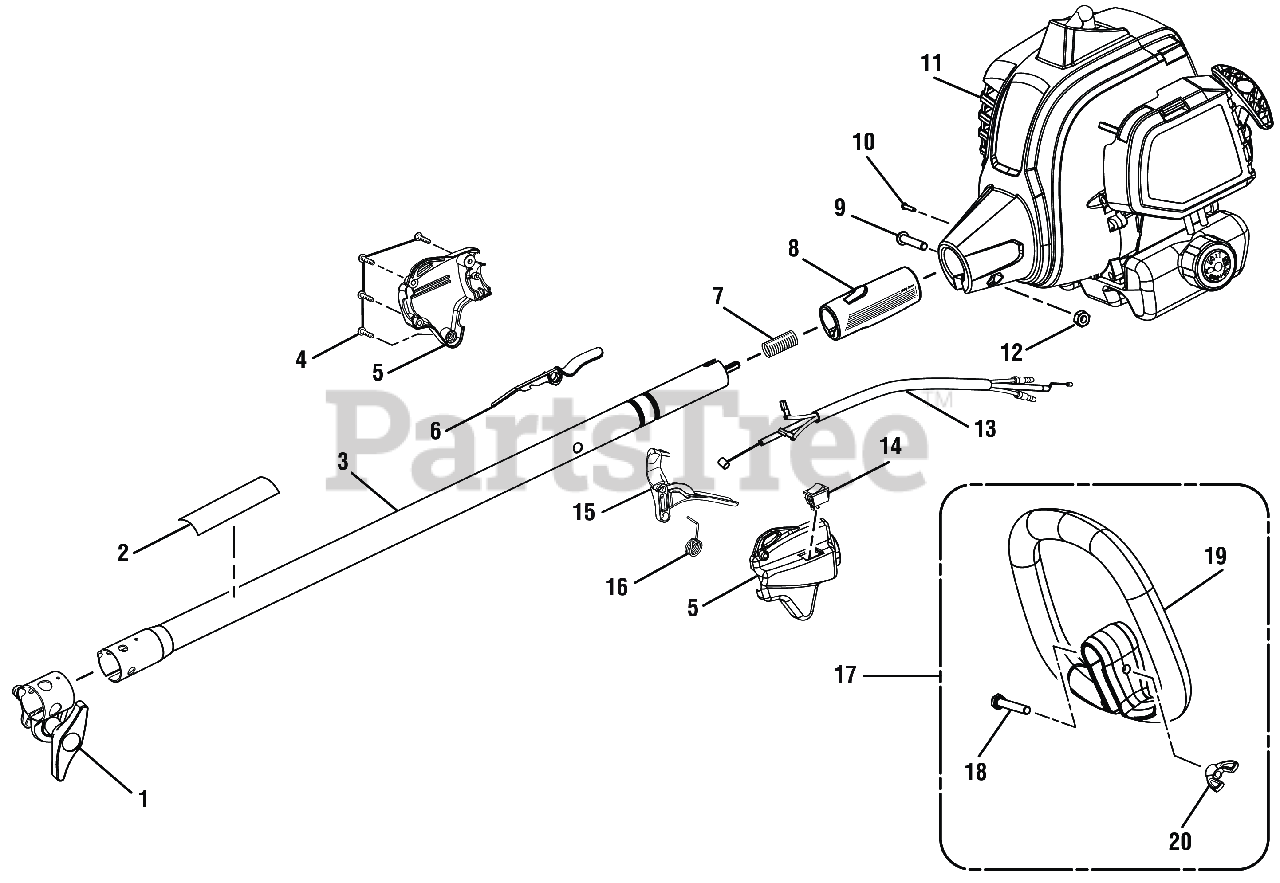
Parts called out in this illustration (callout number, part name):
1	Boom Clamp Assembly
2	Warning Icon Label
3	Upper Boom Assembly
4	Screw (M4 x 20 mm, T20 Torx Pan Hd. S.T.)
5	Control Handle Assembly (Inc. Key No. 6)
6	Trigger Lock
7	COMPRESSION SPRING
8	Rear Handle Grip
9	Screw (M6 x 30 mm, T27 Torx Button Hd.)
10	Screw (M4 x 8 mm, T25 Torx Pan Hd. T.F.)
11	Powerhead Assembly w/Labels
12	Hex Nut (M6.3 x 1)
13	Throttle Cable and Wire Assembly
14	Stop Switch (Momentary Contact)
15	Throttle Trigger
16	Torsion Spring (Throttle Trigger)
17	Auxiliary Handle Assembly
18	Screw (1/4-20 x 40 mm, Cap Hex Hd.)
19	Front Handle
20	Wing Nut (1/4-20, Plastic)
